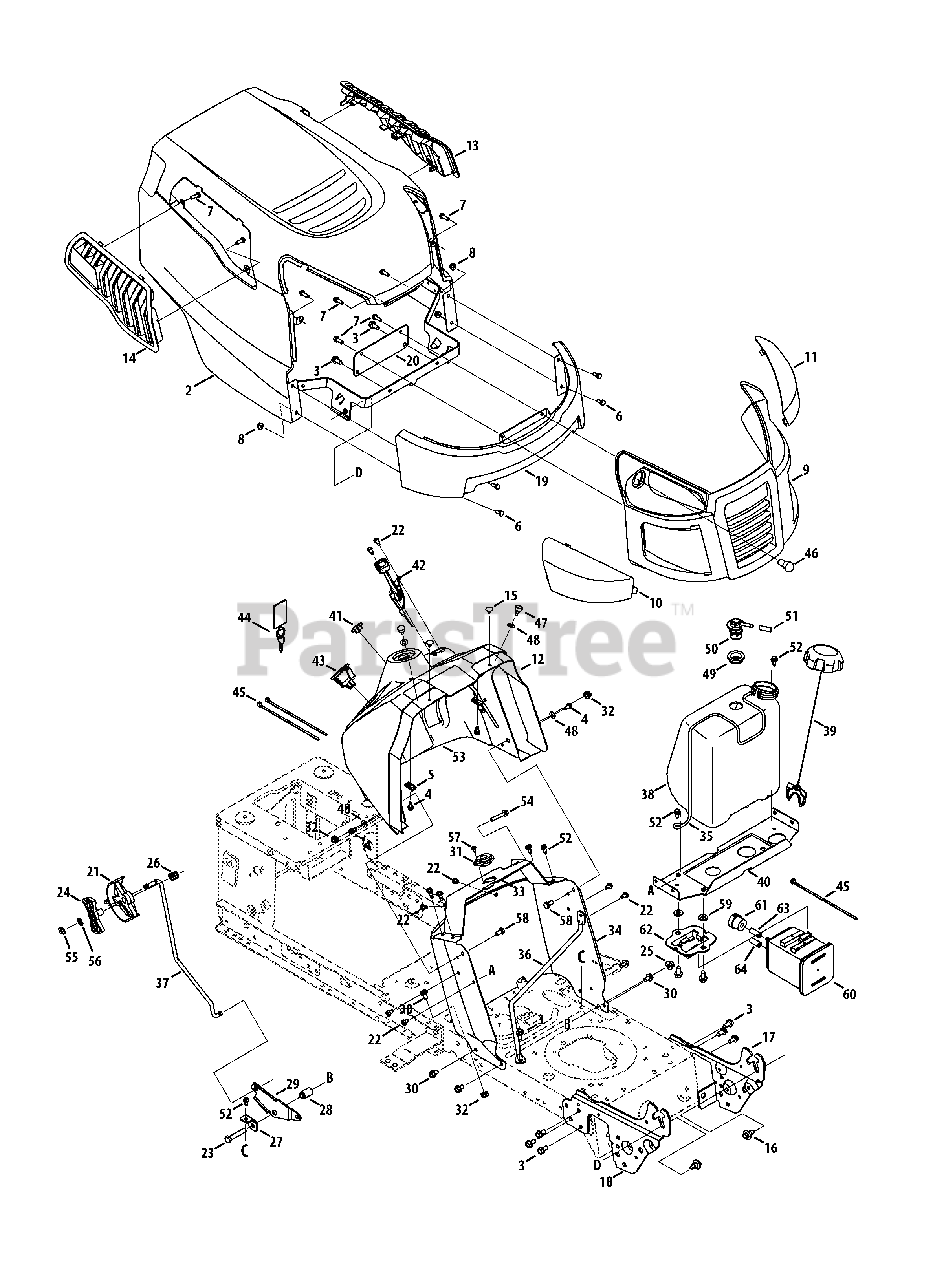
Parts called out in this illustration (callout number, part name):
1	Bulb Socket
2	Hood Assembly
3	Screw, 5/16-18 x .750
4	Hex Washer Screw, 1/4-20 x .500
5	Tin Clip Nut, 1/4-20
6	Hex Screw, 1/4-20 x .620
7	Screw, 1/4 x .750
8	Nut, Hex Flange Insert Lock, 1/4-20
10	Headlight Lens, RH
11	Headlight Lens, LH
12	Dash Collar
13	Hood Scoop, LH
14	Hood Scoop, RH
15	Bumper
16	Shoulder Screw, 5/16-18
17	Left Support Pivot Bracket
18	Right Support Pivot Bracket
19	Lower Grill
20	Lower Grill Bracket
21	Parking Brake Lever
22	Self-Tap Screw, 1/4-20
23	Hex Head Screw, 3/8-16
24	Ferrule, 1/4-20 x 1.00
25	Nut, Hex Flange Insert Lock, 3/8-16
26	Compression Spring
27	Speed Latch Support Tab
28	Flange Spacer
30	Self-Tap Screw, 5/16-18
31	Steering Column Bearing
32	Nut, Hex Flange Lock, 5/16-18
34	Dash
35	Fuel Tank Support Rod
36	Dash support Rod
37	Control Rod
38	Fuel Tank
39	Fuel Cap
40	Gas Tank Support Bracket
41	Choke Plug
42	Throttle/Choke Assembly
43	Key Switch Module
44	Key Assembly
45	Cable Tie
46	Headlight Bulb
47	Ratchet Clip, .250 x .500
48	Flat Washer, .25 x .630 x .0515
49	Rubber Grommet
50	Fuel Rollover Valve
51	Vent Hose
52	Hex Washer Screw, 1/4-20 x .625
53	Upper Dash
54	Hex Flange Bolt
55	Top Lock Weldnut
56	Lock Washer
57	Screw, #10
58	Hex Head Screw, 5/16-18
59	Flat Washer
60	Carbon Cannister
61	Cannister Vent Filter
62	Cannister Adapter Bracket
63	Low Perm. Fuel Hose, 3/16 White
64	Low Perm. Fuel Hose, 7/32 Yellow
